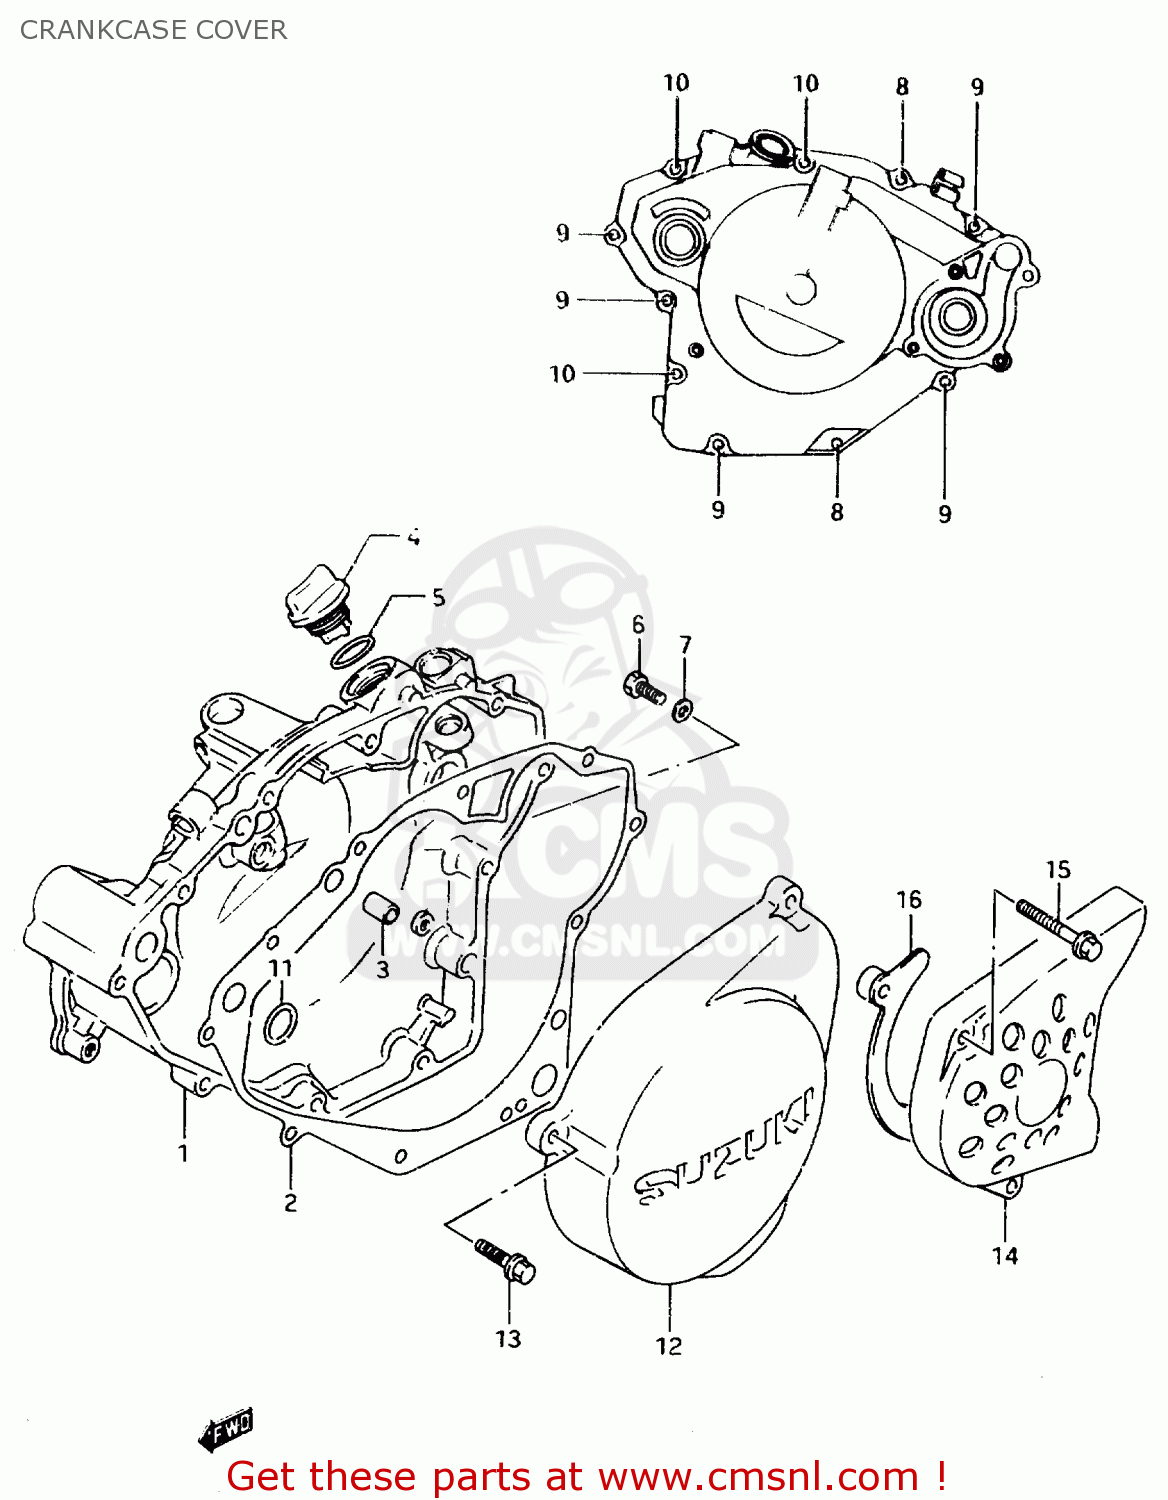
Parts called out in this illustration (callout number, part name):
1	COVER, CLUTCH
2	GASKET,CLUTCH COVER (NAS)
3	PIN
4	PLUG,OIL FILLE
5	O RING(D:3.1,ID:16.8)
6	SCREW(6X10)
7	GASKET(6.2X11X1) (NAS)
8	BOLT
9	BOLT
10	BOLT
11	O RING(D:1.9,ID:14.5)
12	COVER,MAGNETO
13	BOLT
14	COVER,SPROCKET
15	BOLT
16	PLATE,FR CHAIN GUIDE
